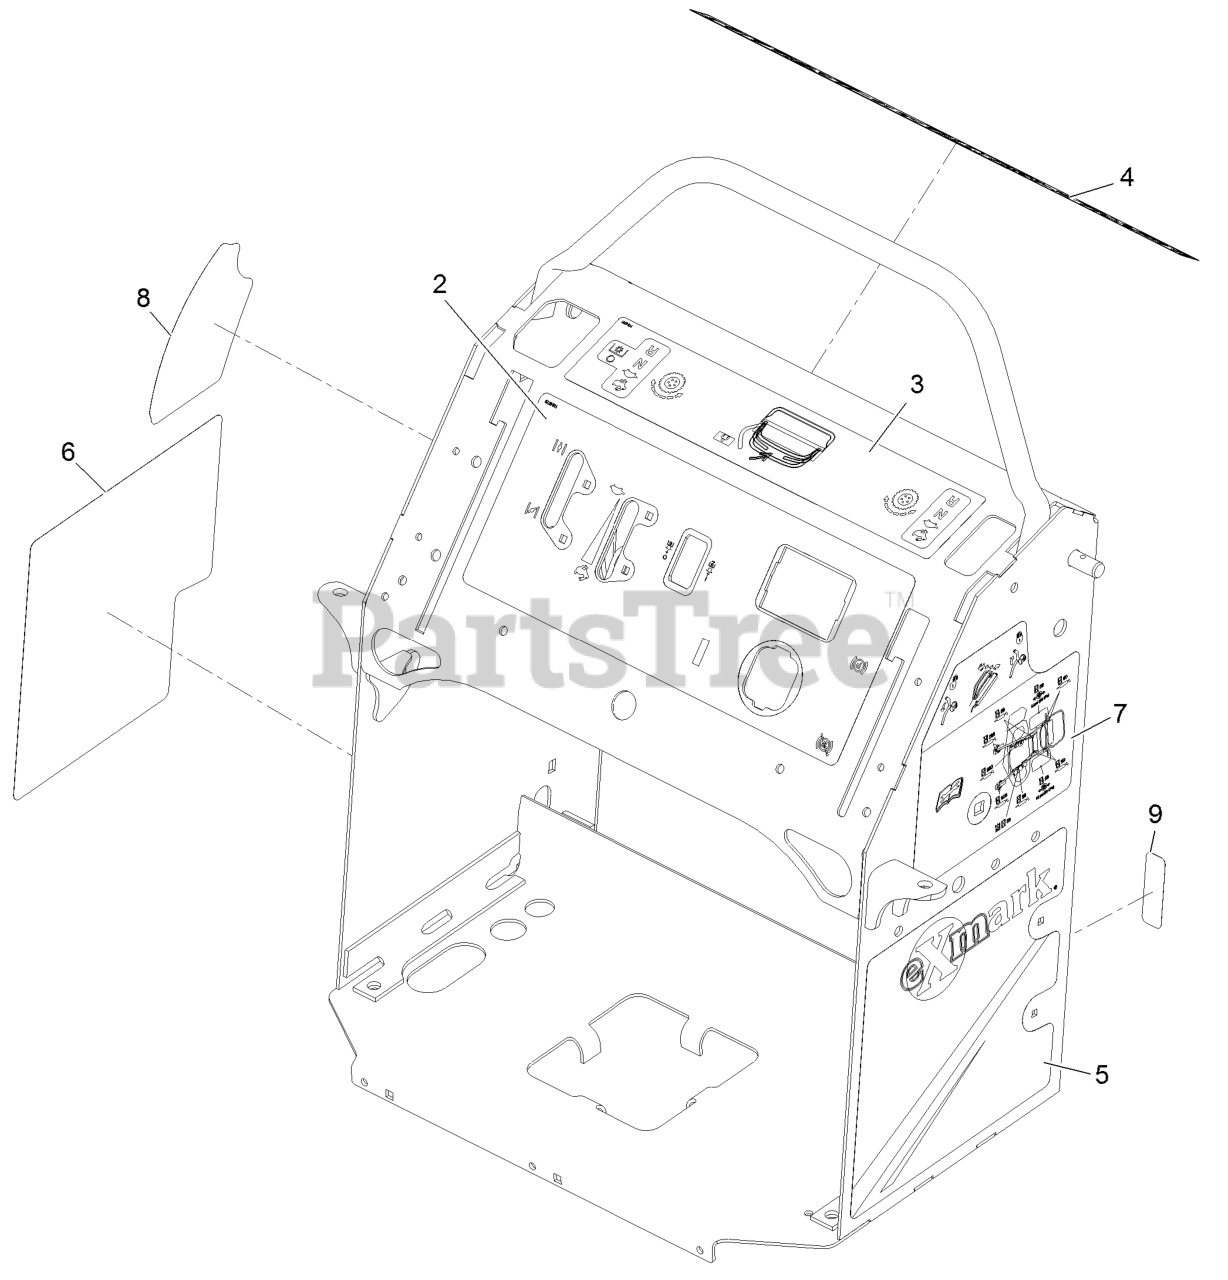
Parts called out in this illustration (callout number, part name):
2	DECAL-CONTROL PANEL
3	DECAL-MOTION CONTROL
4	DECAL-WARNING
5	DECAL-LH PANEL
6	DECAL-RH PANEL
7	DECAL-SERVICE AID
8	DECAL-HEIGHT OF CUT
9	DECAL-FUSE
